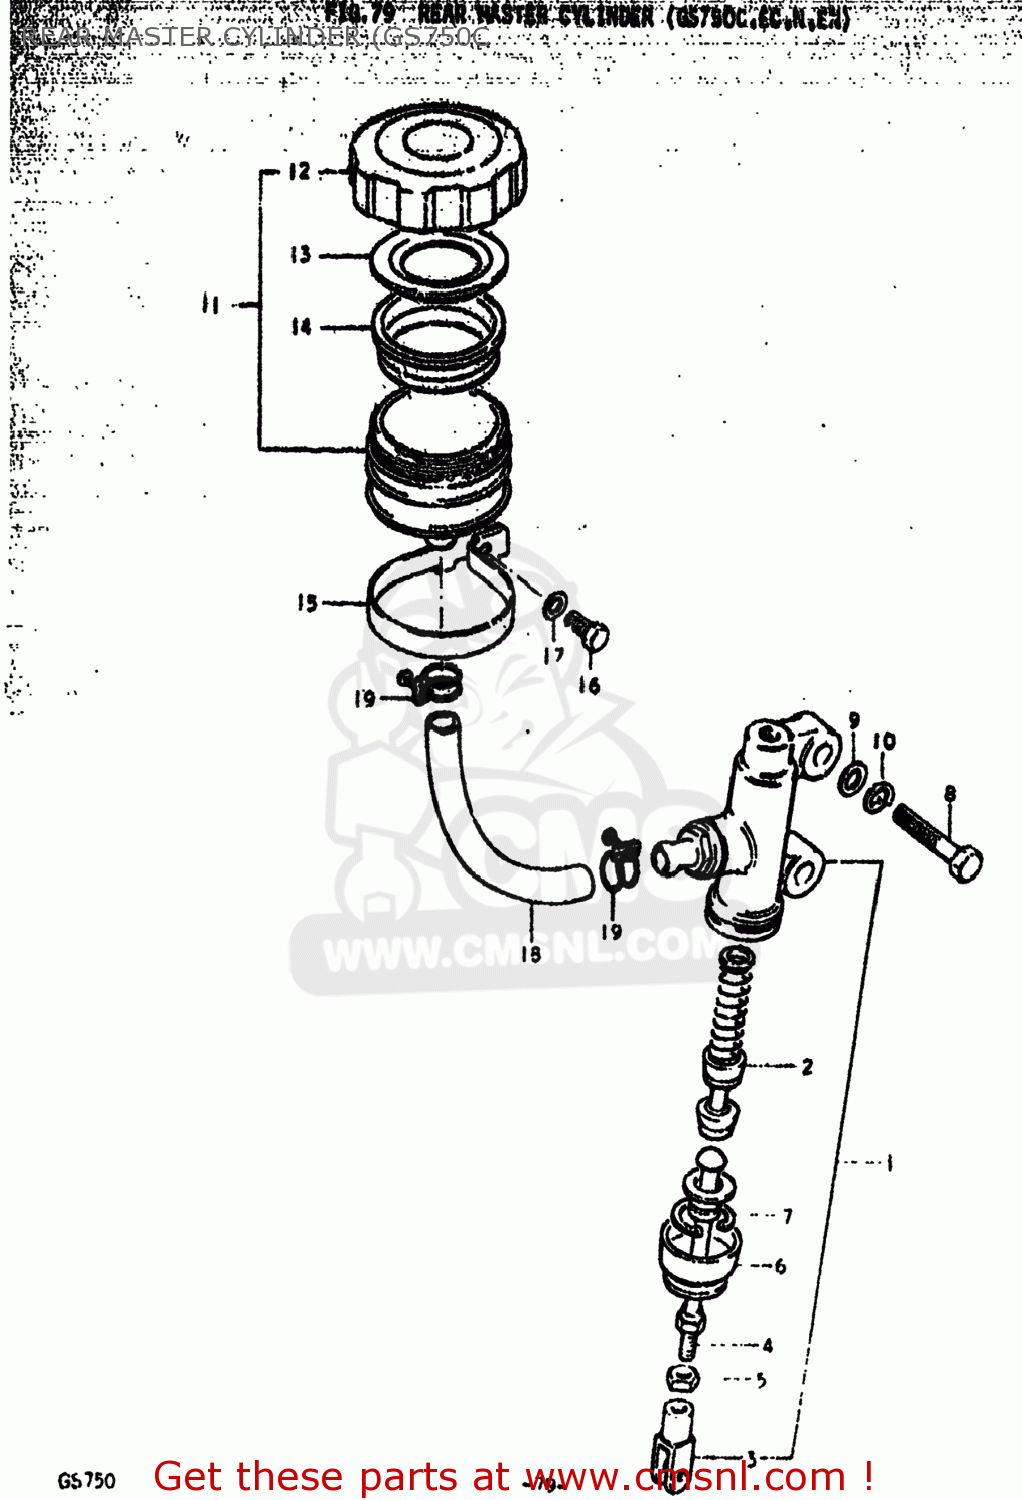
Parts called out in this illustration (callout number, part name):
1	CYLINDER ASSEMBLY,REAR MASTER
2	PISTON/CUP SET
3	YOKE
4	ROD,PUSH
5	NUT
6	BOOT
7	CIRCLIP
8	BOLT (8X30)
9	WASHER
10	LOCK WASHER
11	TANK ASSEMBLY,RESERVOIR
12	CAP
13	PLATE,DIAPHRAGM
14	DIAPHRAGM
15	CLAMP
16	BOLT, UPPER
17	LOCK WASHER
18	HOSE,RESERVOIR TANK
19	CLAMP
